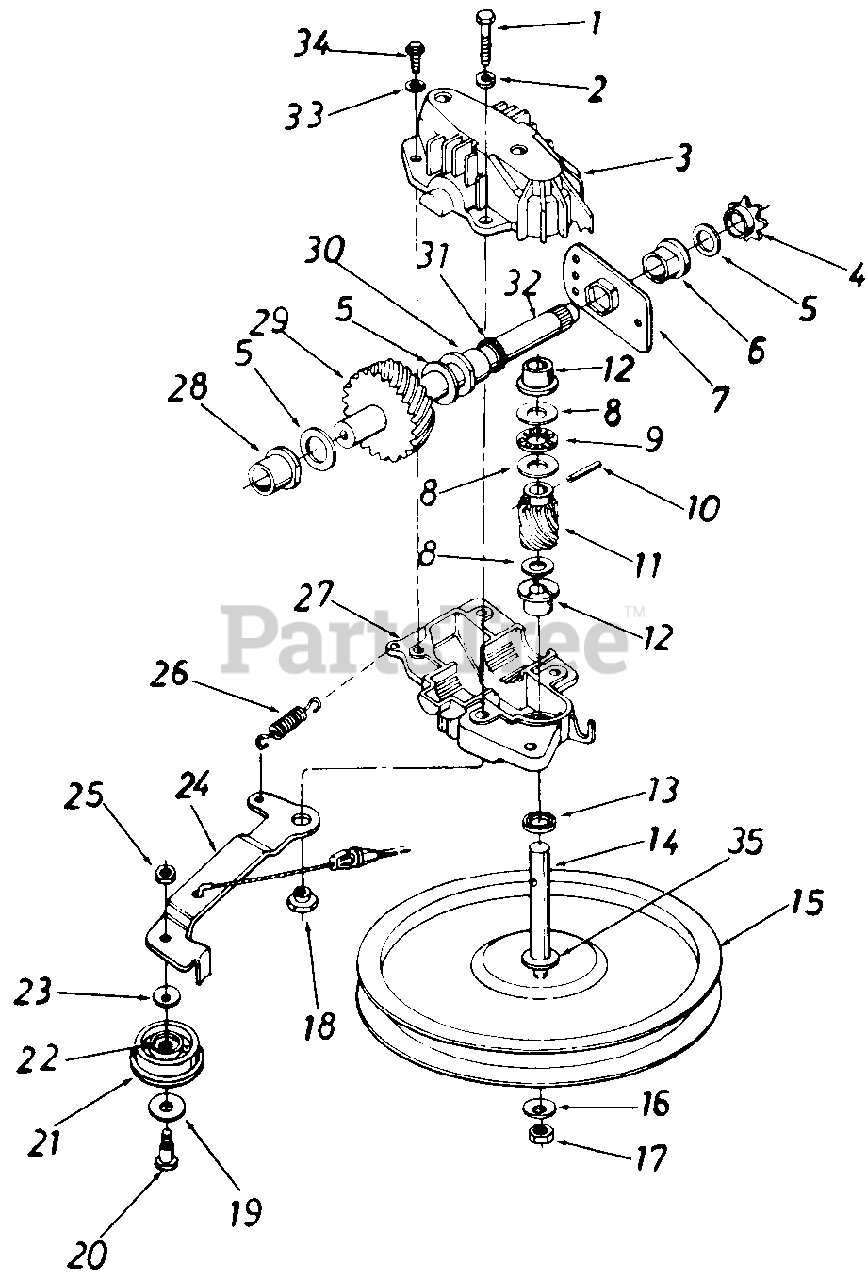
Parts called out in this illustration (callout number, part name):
1	Hex Bolt 1/4-20 x 1.25" Lg.
2	L-Wash. 1/4" I.D.
3	Upper Hsg. Half
4	#48 Sprocket 7 Tooth x 1/2 Pitch
5	Fl-Wash. 518" I.D. x .030
6	Hex Flange Brg. .631" I.D.
7	Hex Bearing Cup
8	Thrust Wash. .382" I.D. x .70" O.D.
9	Thrust Bearing .375" I.D. x .812" O.D.
10	Spring Pin Spir. 1/8" x .62" Heavy
11	11 Tooth Helical Gear
12	Flange Bearing
13	Oil Seal
14	Pulley-Transmission Shaft
15	Fl-Pulley 5.06" O.D.
16	BellWash. .265" I.D. x 75"
17	Hex L-Nut 1/4-28 L.H. Thd.
18	Shld. Spacer .375" Dia. x . 170
19	Fl-Wash. .390" I.D. x 1.0"
20	Shld. Bolt .375" Dia. x .40"
21	Fl-ldler Plastic 1.50" Dia.
22	Needle Brg. .375" x .31
23	Bell-Wash. .265" I.D. x 75"
24	Idler Brk't. Ass'y.
25	Hex Patch L-Nut 1/4-28 Thd.
26	Extension Spring 1.12" Lg.
27	Lower Hsg. Half
28	Flange Bearing .566 Dia.
29	33 Tooth Helical Gear
30	Flange Bearing .629 Dia.
31	Oil Seal .625 Dia.
32	Gear Sprocket Shaft
33	L-Wash. #10 I.D.
34	Hex B-Tap Scr. #10 x .62"
35	Hex Washer .26" x .88"
